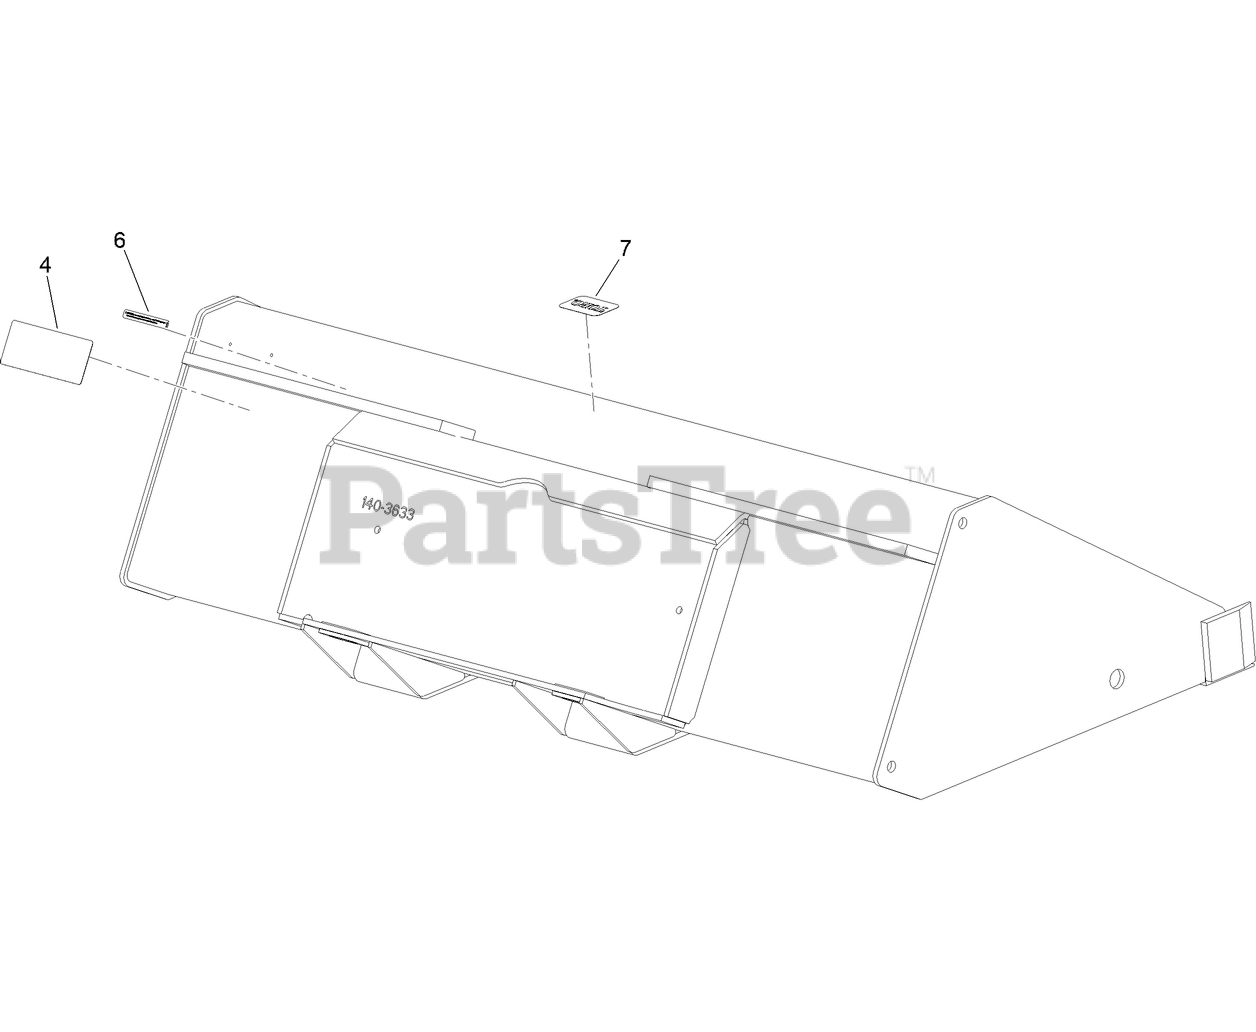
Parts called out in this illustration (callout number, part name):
4	DECAL-CAPACITY
6	DECAL-WARNING
7	DECAL
